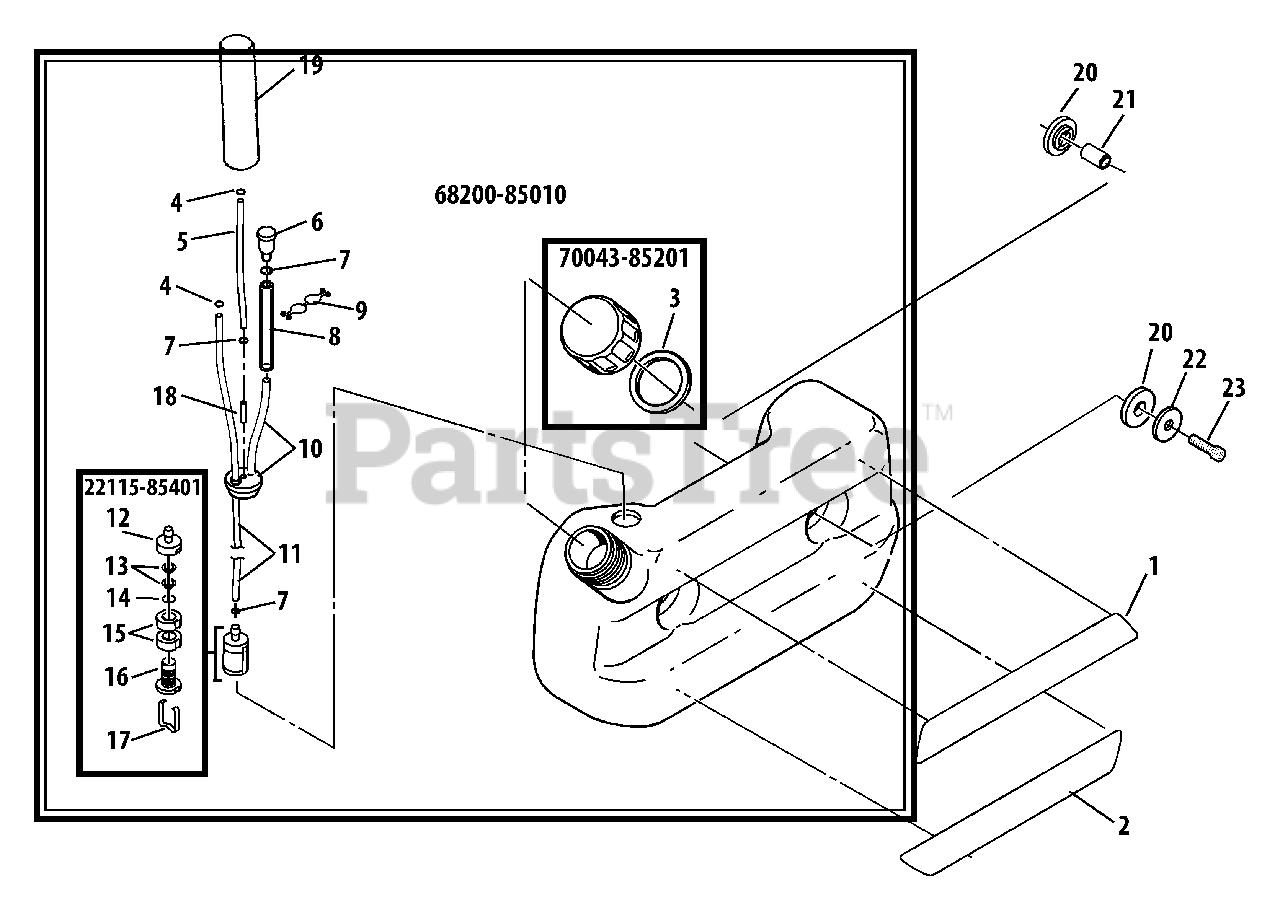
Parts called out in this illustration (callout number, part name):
1	LABEL - MODEL
2	LABEL - SHINDAIWA
3	GASKET, CAP
4	CLIP
5	TUBE
6	VENT, FUEL TANK
7	RING, RETAINING - 6
8	TUBE
9	CLIP
10	PIPE ASSY
11	TUBE
12	WEIGHT, FUEL FILTER
13	SCREEN, FILTER
14	RING, RETAINING
15	FILTER, FUEL
16	CASE, FILTER
17	CLIP, FILTER
18	CONNECTOR, PIPE
19	TUBE
20	CUSHION
21	BUSHING
22	COLLAR
23	SCREW - 6X25
22115-85401	FILTER, FUEL
68200-85010	FUEL TANK ASSY
70043-85201	CAP ASSY
